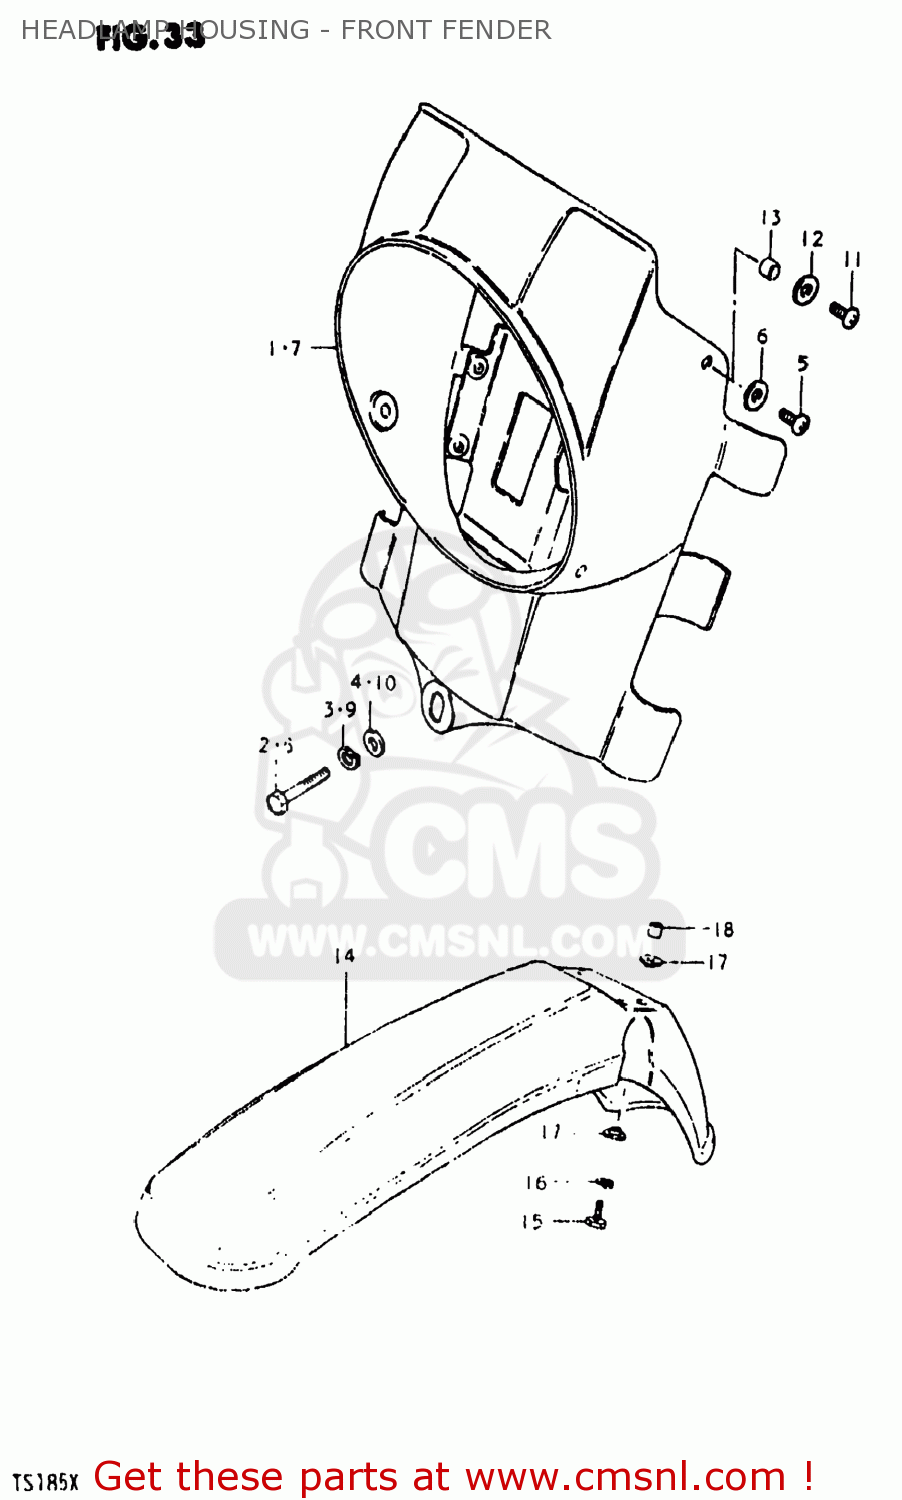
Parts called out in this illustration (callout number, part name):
1	HOUSING,HEADLAMP
2	BOLT
3	LOCK WASHER
4	WASHER
5	SCREW
6	WASHER (5.5X16X1.2)
7	HOUSING,HEADLAMP
8	BOLT
9	LOCK WASHER
10	WASHER
11	SCREW
12	WASHER (5.5X18X1.6)
13	SPACER (5.5X8X4)
14	FENDER,FRONT
15	BOLT
16	LOCK WASHER
17	SPACER
18	SPACER
